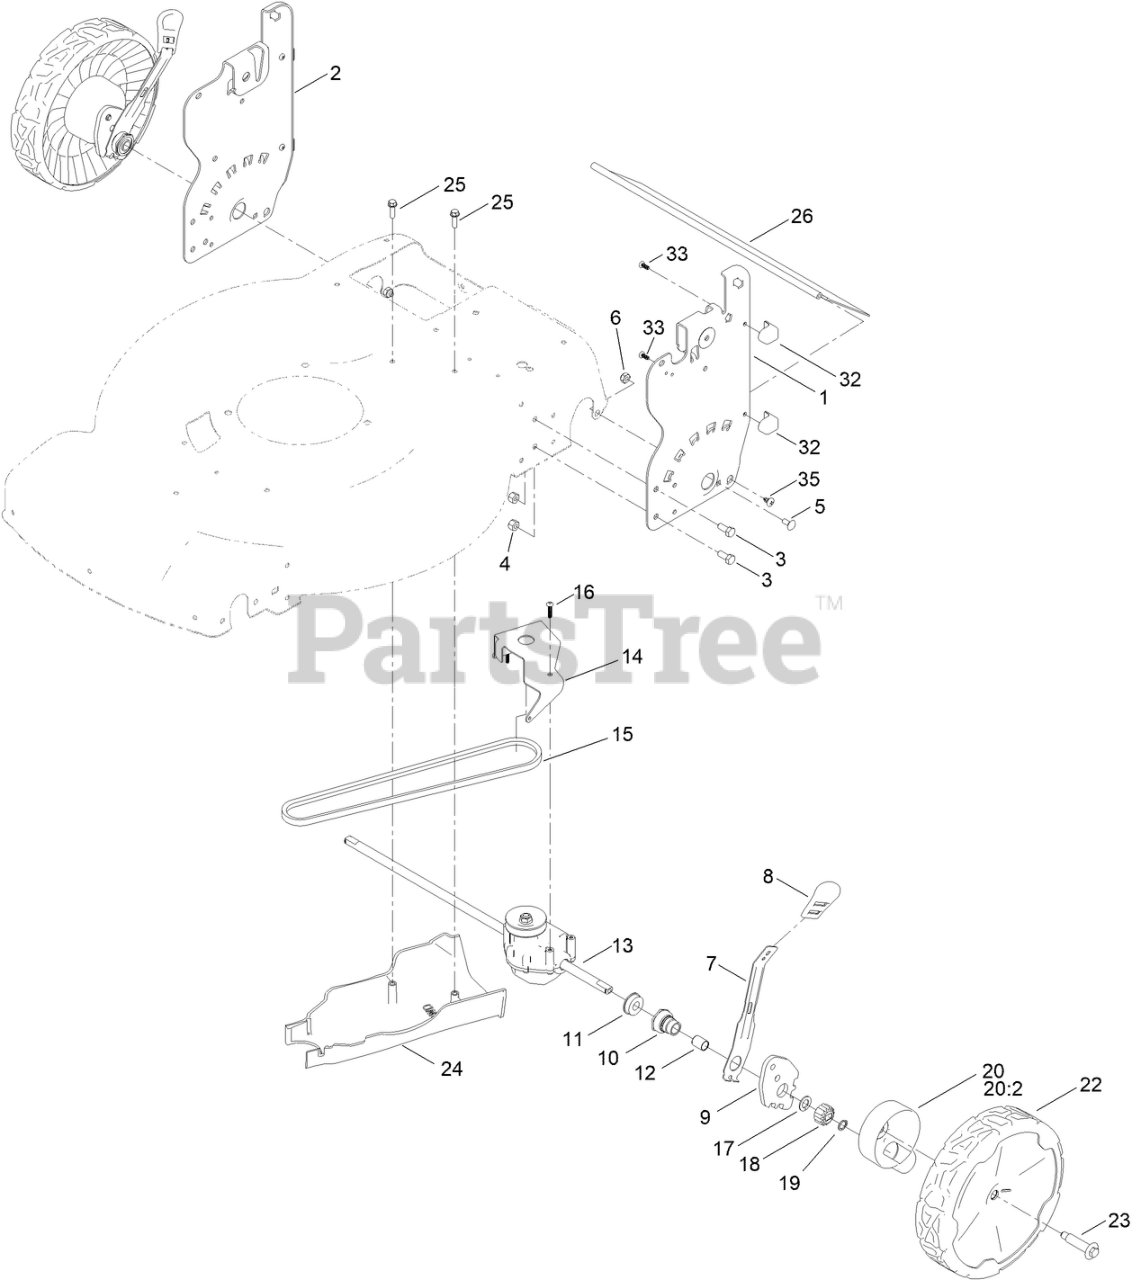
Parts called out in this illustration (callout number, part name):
1	PLATE-HOC, LH
2	PLATE-HOC, RH (2 HOLE)
3	SCREW-HH
4	NUT-LOCK, NI
5	SCREW-CARR
6	NUT-LOCK, NI
7	ARM-SPRING
8	KNOB-HOC
9	ARM-PIVOT, REAR
10	RETAINER-BUSHING, HOC
11	BEARING-BALL
12	BUSHING-SLEEVE
13	TRANSMISSION-RWD
14	BRACKET-TRANSMISSION
15	V-BELT
16	SCREW-PLASTITE
17	WASHER-THRUST
18	GEAR-PINION, 15T
19	RING-RETAINING
20	ASM-COVER, GEAR (DK GRAY)
20:2	WASHER-STEPPED
22	ASM-9.65" WHEEL, GEARED
23	WHEEL BOLT
24	COVER-BELT, RWD
25	SCREW-HWH
26	SHIELD-TRAILING
32	PAD-SMART STOW
33	SCREW-PLASTITE
35	SCREW-PTH
